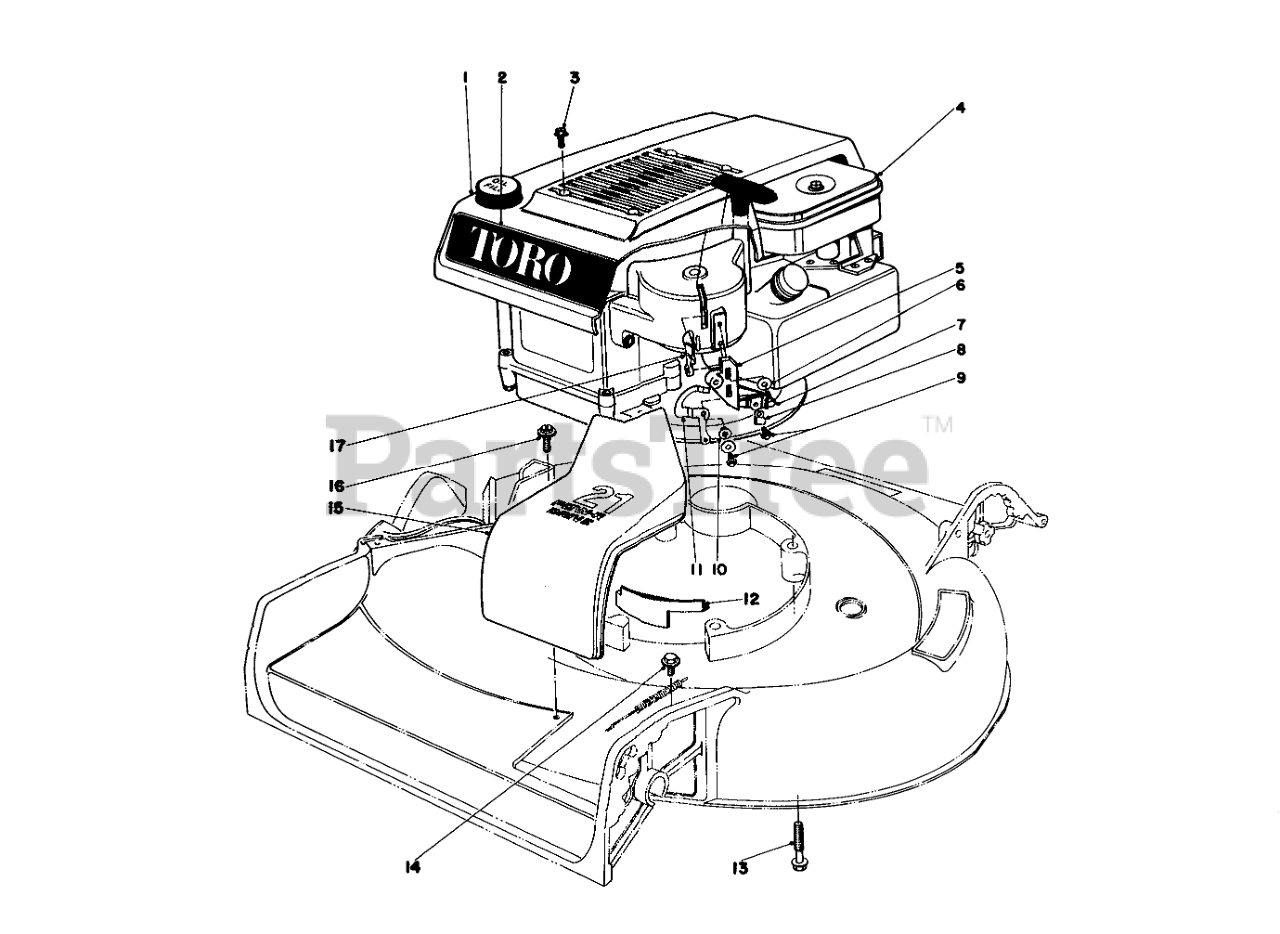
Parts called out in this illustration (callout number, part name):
1	Shroud
2	Decal-Toro
3	8X1/2 SELF TAP SCREW
4	Engine
5	CABLE & PIVOT BLOCK
6	WASHER-FLAT
7	Screw
8	CLAMP
9	Screw
10	BUSHING
11	CAM INTERLOCK
12	HOUSING CAP
13	3/8-16 X 2-3/4 CAPSCR
14	SCREW-HWHTF
15	BELT DRIVE COVER
16	SCREW
17	INTERLOCK LEVER
